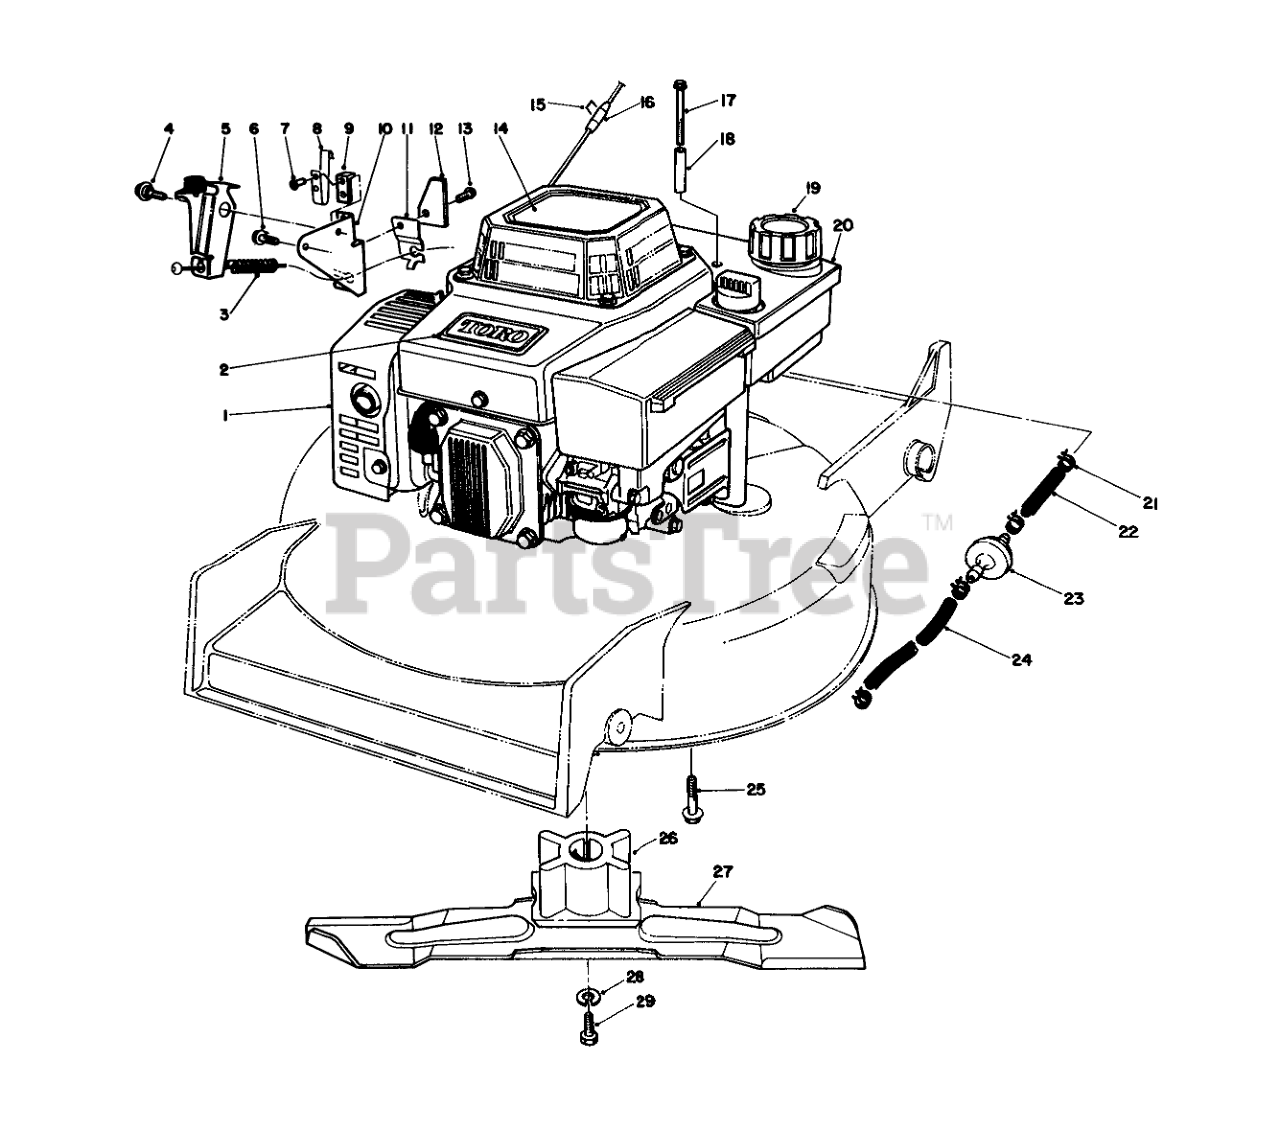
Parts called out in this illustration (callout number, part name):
1	Engine
2	TORO LOGO PLT
3	SPRING-COMPRESSION
4	Screw-Shoulder
5	BRAKE PLATE ASM
6	THO FORM SCREW M6 X 1
7	RIVET-PLASTIC
8	STRAP-GROUND
9	Strap-Insulation
10	Plate-Mounting
11	CABLE CLAMP
12	STOP-GROUND STRAP
13	SCREW
14	DECAL - RECOIL GTS
15	Staple
17	THRD FORMING SCREW
18	TUBULAR SPACER
19	GAS CAP ASM
20	TANK ASM
21	CLAMP-FUEL LINE
22	LINE-GAS
23	FILTER-FUEL
24	HOSE-FUEL
25	SCREW-HWHTF
26	BLADE RETAINER
27	BLADE-21in
28	WASHER-LOCK
29	SCREW-BLADE
